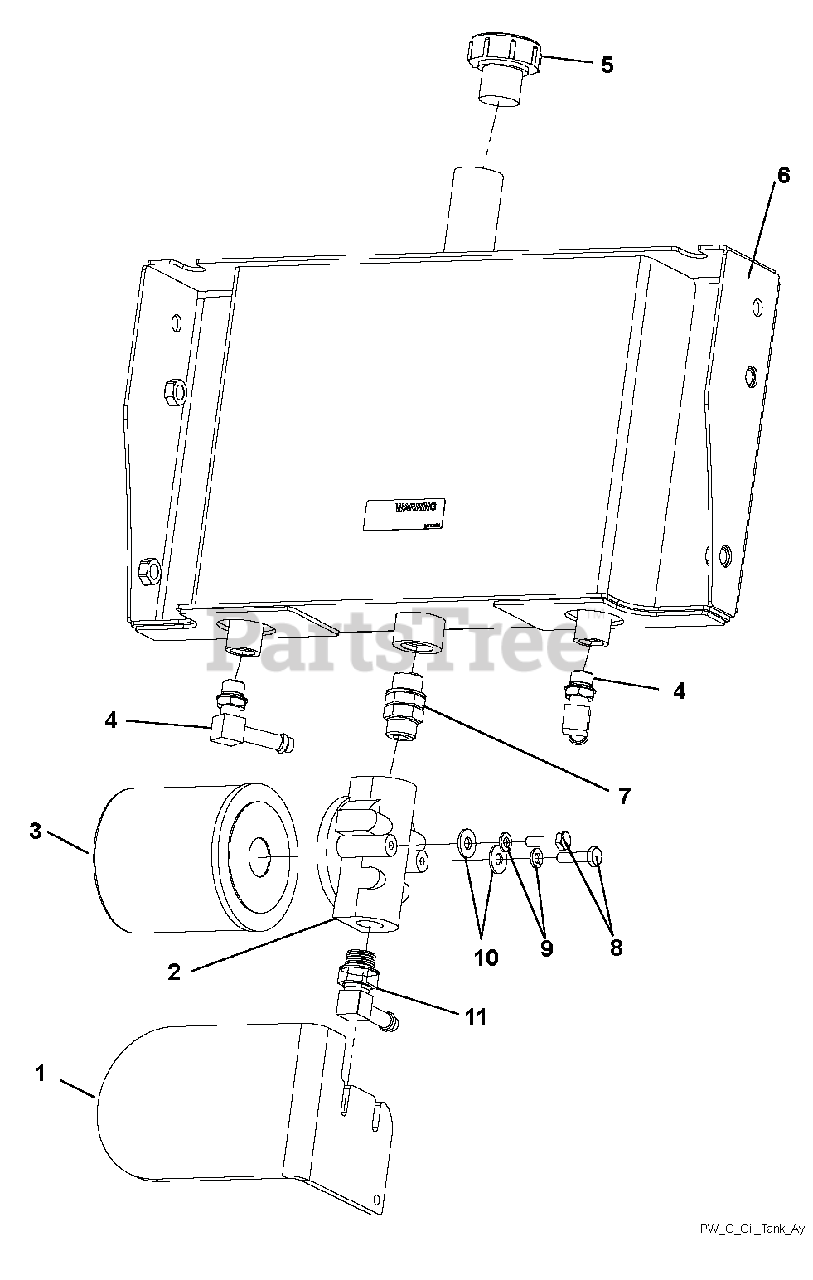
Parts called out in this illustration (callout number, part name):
1	GUARD, HYDRO FILTER FLWLK
2	HEAD, OIL FILTER
3	FILTER, OIL
4	FTG, 90 9/16MOR X 3/8HOSE
5	CAP, OIL FILL BREATHER
6	WLDT, TANK
7	FTG, STR UNION M80-M80
8	BLT-HEX .25-20X1.00 GR5 YWZC
9	Washer, .250 Medium Spring Lock
10	WSHR-FL-STL.312X.734X.065 YWZ
11	FTG, 90 BRB-OR 4601-06-08
